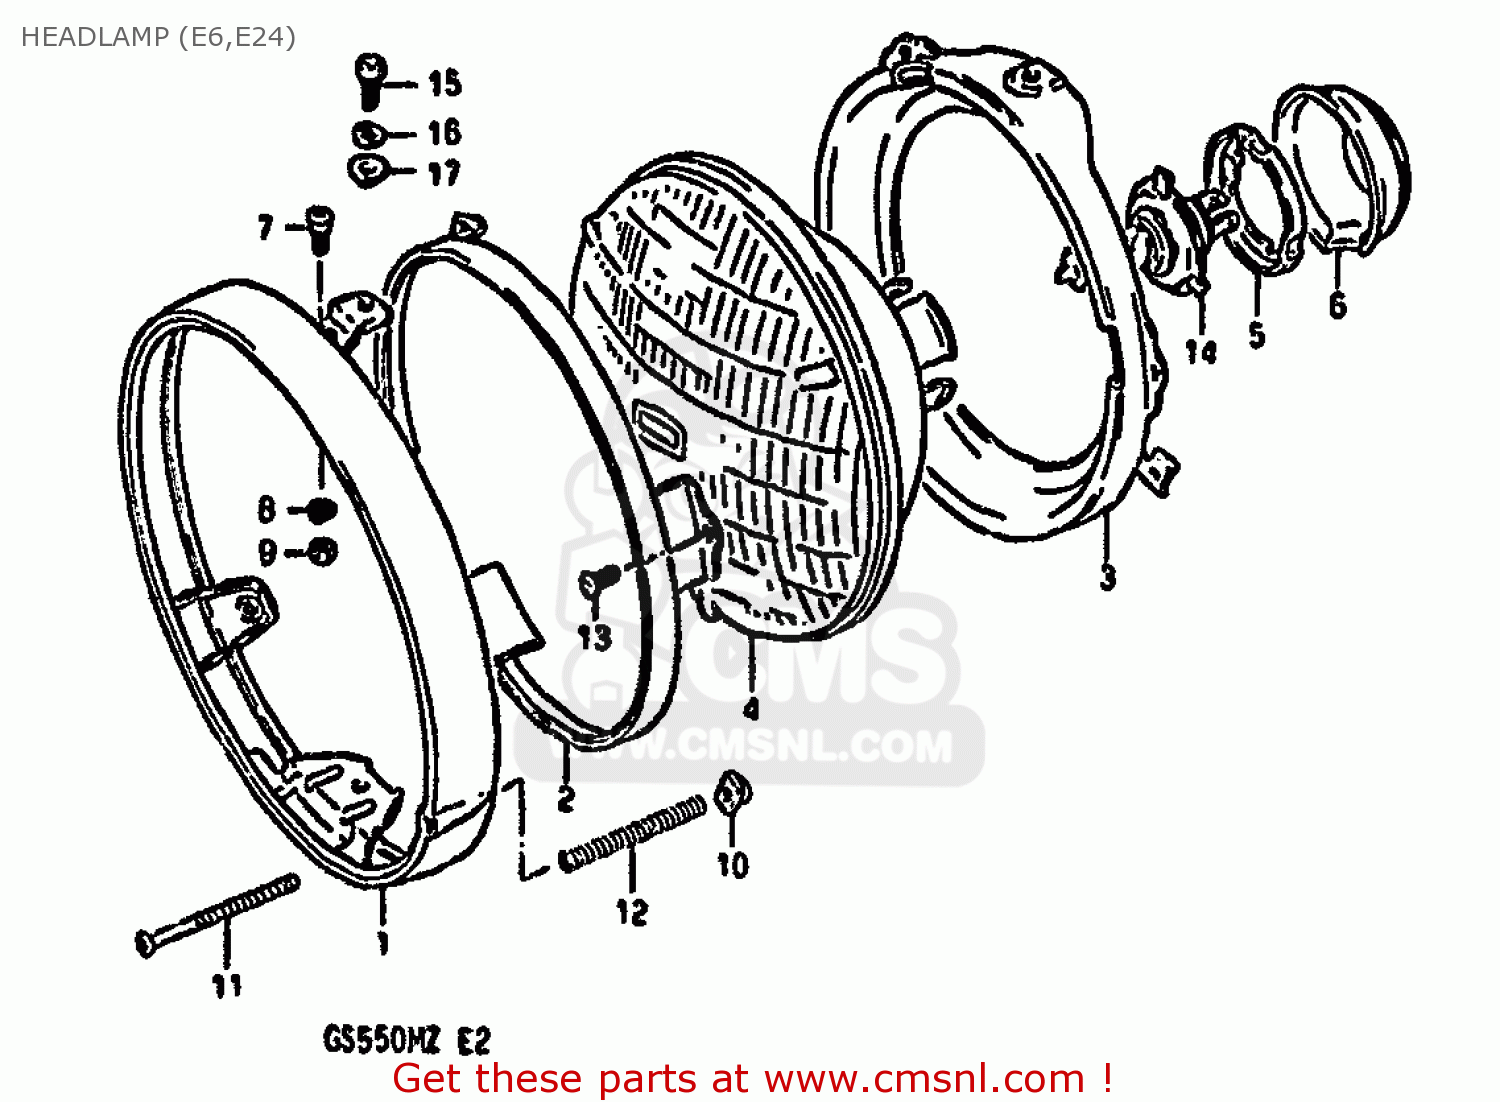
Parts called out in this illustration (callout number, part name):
1	RIM,HEADLAMP
2	RETAINING RING
3	RING
4	LAMP UNIT
5	SETTING,BULB
6	COVER,HEADLAMP SOCKET
7	H/LAMP LENS UNIT FITING SCRE
8	LOCK WASHER
9	NUT
10	NUT
11	SCREW,HEADLAMP ADJUST
12	SPRING,ADJUSTING
13	SCREW
14	BULB(12V60/55W,H4)
15	SCREW
16	WASHER,LOCK
17	WASHER
